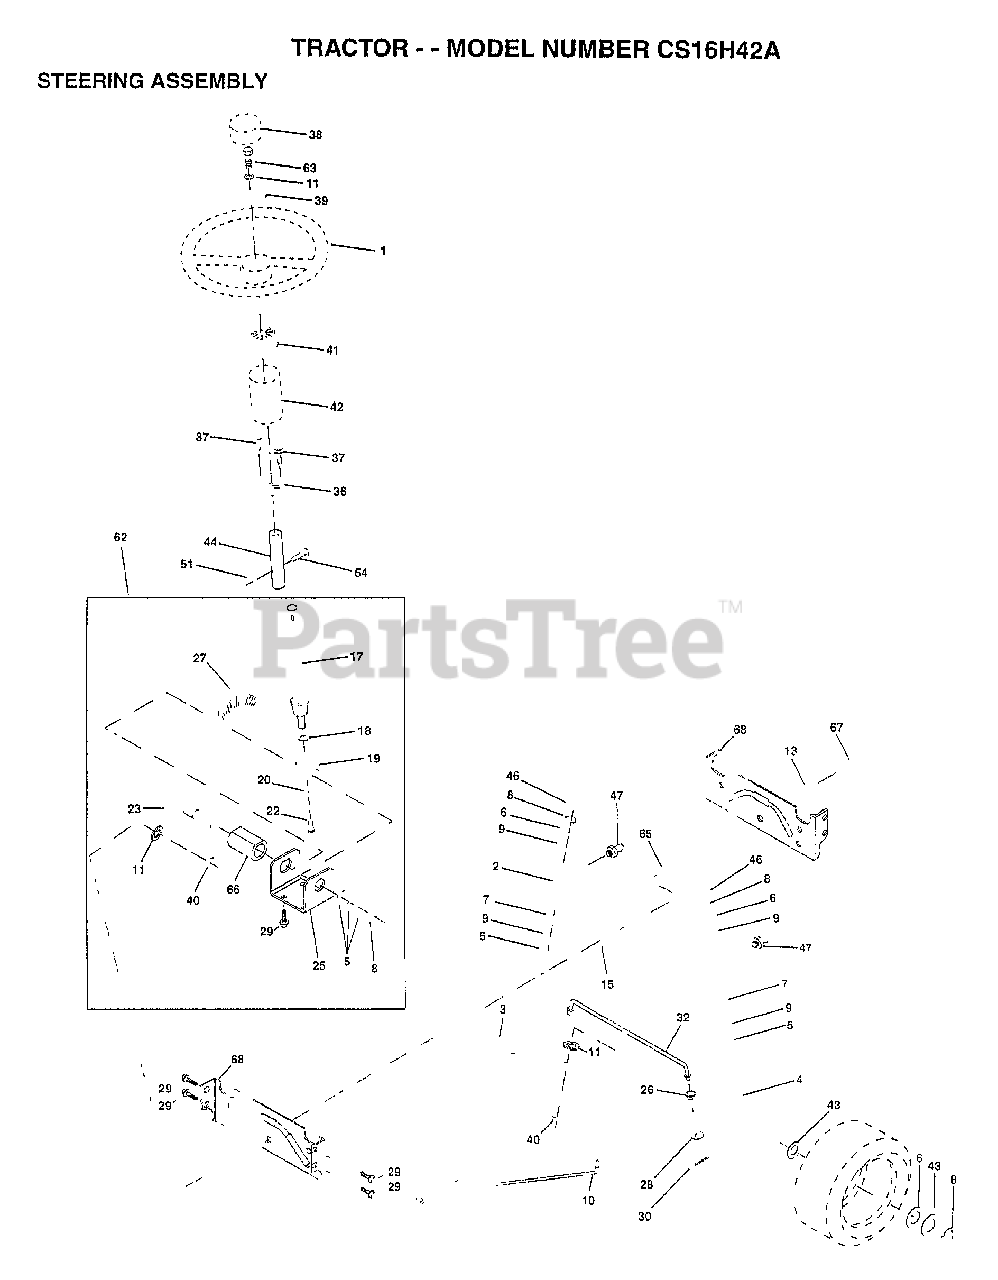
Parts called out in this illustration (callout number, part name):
1	WHEEL STR AYP BLK
2	AXLE ASM
3	SPINDLE.ASM.LH
4	"SPINDLE ASM,RH"
5	WASHER .T
6	WASHER
7	WASHER
8	RING
9	COL. SRTG. BEAR.
10	DRAGLINK-STAMPED
11	LOCKWASHER
13	BEARING AXLE
15	"NUT-LOC,FLANGE LT"
17	SHAFT ASM STEERIN
18	THRUST WASHER
19	SUPPORT.SHAFT
22	SCREW HEX SOC1/4-
25	BRKT-STEERING
26	BUSHING.DRAGLINK
27	GEAR SECTOR
28	WASHER
29	SCREW
30	COTTER PIN
32	TIE ROD
36	BUSHING.STEERING
37	"SCREW-TT,10-32 FL"
38	CAP STEER AYP
39	WASHER T
40	GRIPCO NUT
41	ADAPTER LT
42	BOOT.STEER.PL
43	WASHER
44	EXT SHAFT STEERIN
46	CAP
47	ZERK M
51	NUT
54	BOLT
62	KIT STEERING ASM
63	BOLT
65	SPACER AXLE
66	"BEARING-ARM,PITMA"
67	BOLT
68	BRACE AXLE
